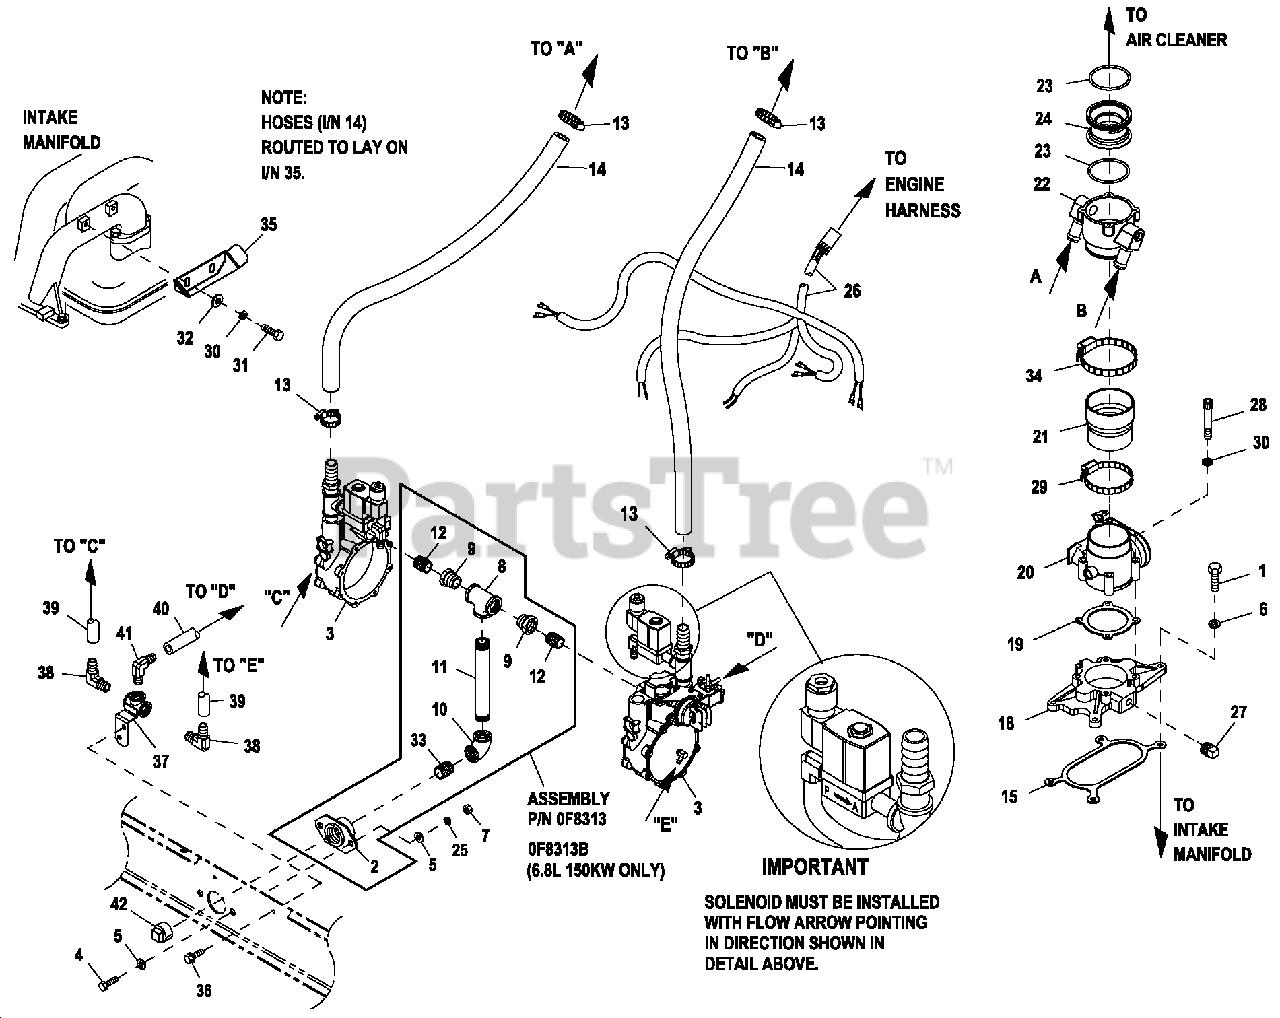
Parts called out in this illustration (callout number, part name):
1	SCREW HHC 5/16-18 X 1-1/4 G5
2	SUPPORT NAT GAS SOLENOID
3	REG 6.8L 100 KW LP CPL EMISS
4	SCREW HHC M12-1.75 X 30 C8.8
5	WASHER FLAT 1/2 ZINC
6	WASHER LOCK M8-5/16
7	NUT HEX M12-1.75 G8 YEL CHR
8	PIPE TEE 1-1/4 NPT
9	BSHG RDCR HEX 1-1/4-3/4
10	ELBOW 90D 1-1/4 NPT
11	NIPPLE PIPE 1-1/4 NPT X 3 (100 KW & 130KW)
12	NIPPLE CLOSE 3/4 X 1.375
13	CLAMP HOSE #10 .56-1.06
14	HOSE 3/4 ID SAE-30R2 (45" LG)
15	GAS KET ADAPTER THROT BODY
18	ADAPTOR THROTTLE BODY
19	GAS KET GOVERNOR ACTUATOR
20	ACTUATOR BOSCH 60 GOVERNOR
21	REDUCER 3.0" TO 2.75" TURBO
22	MIXER 40/60MM ACTUATOR ASSY
23	O-RING 2-3/4 X 3/32 X 2-15/16
24	VENTURI THROTTLE 42MM (6.8L 100 KW)
25	WASHER LOCK 1/2
26	HARNESS FUEL JUMPER DUAL REG
27	PLUG STD PIPE 1/4 STEEL SQ HD
28	SCREW SHC M6-1.0 X 50 C8.8
29	CLAMP HOSE #44 2.31-3.25
30	WASHER LOC K M6-1/4
31	SCREW HHC M6-1.0 X 20 G8.8
32	WASHER FLAT M6
33	NIPPLE CLOSE 1.25 NPT X 1.625
34	CLAMP HOSE #52 2.81-3.75
35	BRACKET, HOSE RISER
36	SCREW THF M6-1 X 16 N WA Z/JS
37	PIPE TEE W/ BRAC KET WELDED
38	BARBED EL 90 3/16X1/8
39	HOSE VACUUM 5/32 (12.0"LG)
40	HOSE VACUUM 5/32 (10.5"LG)
41	BARBED EL W/VENT (.052")
42	PLUG PIPE 1.25 SQ HD ZINC
